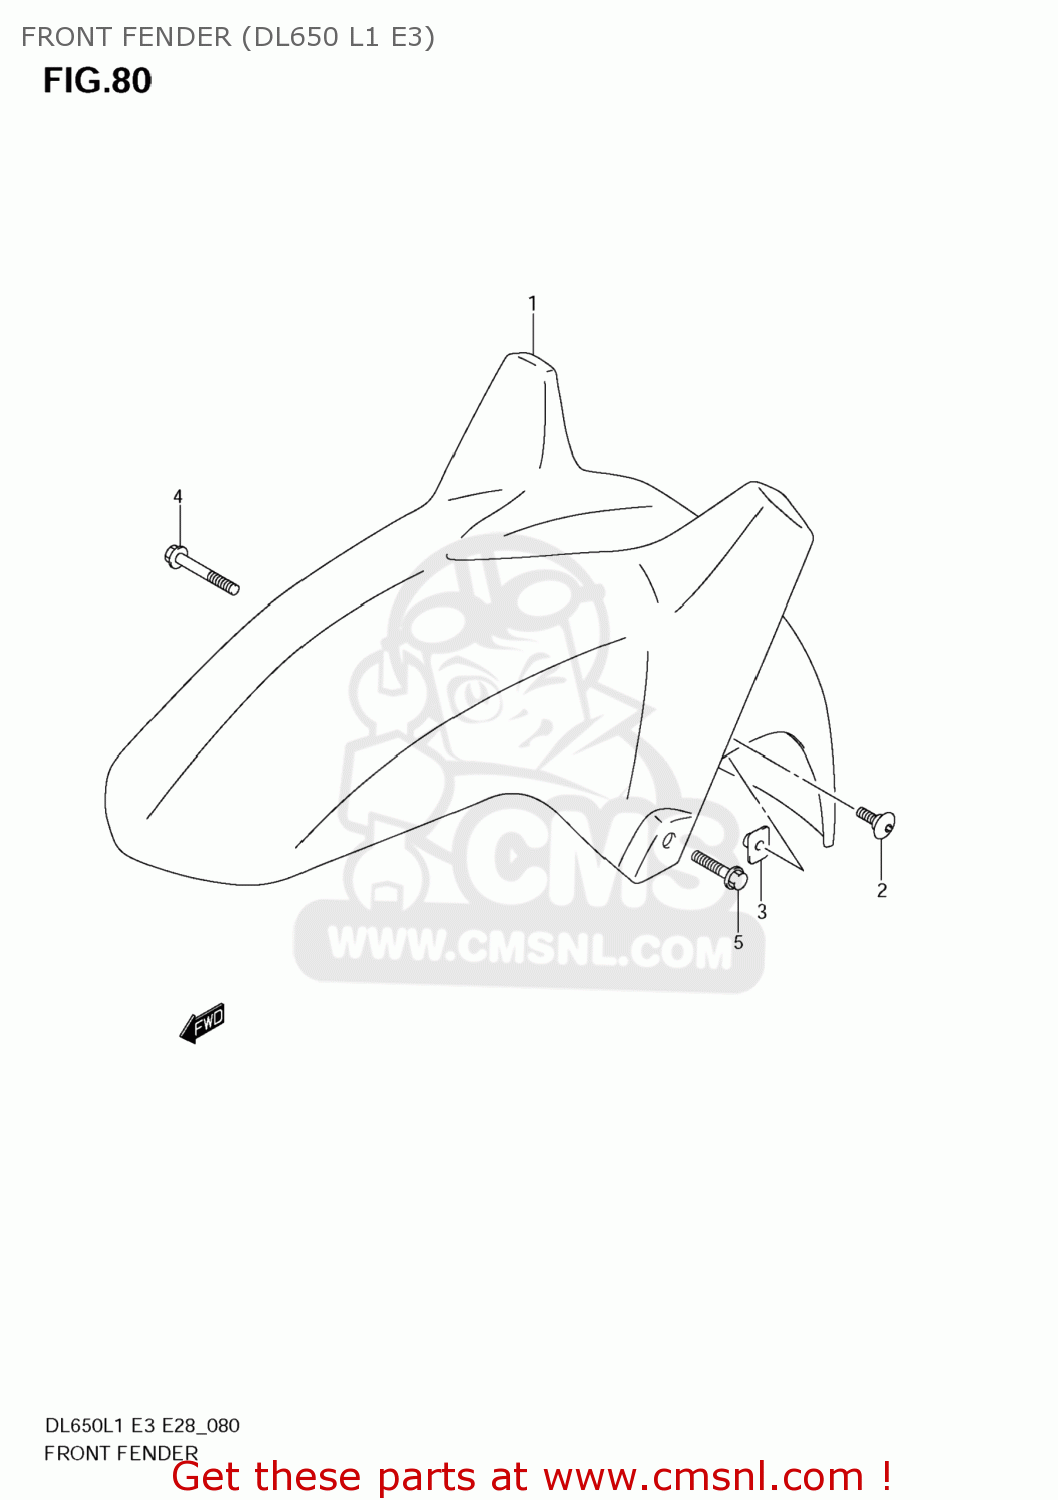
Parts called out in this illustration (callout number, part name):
1	FENDER,FR
2	SCREW(6X16)
3	NUT,FR FENDER
4	BOLT
5	BOLT
